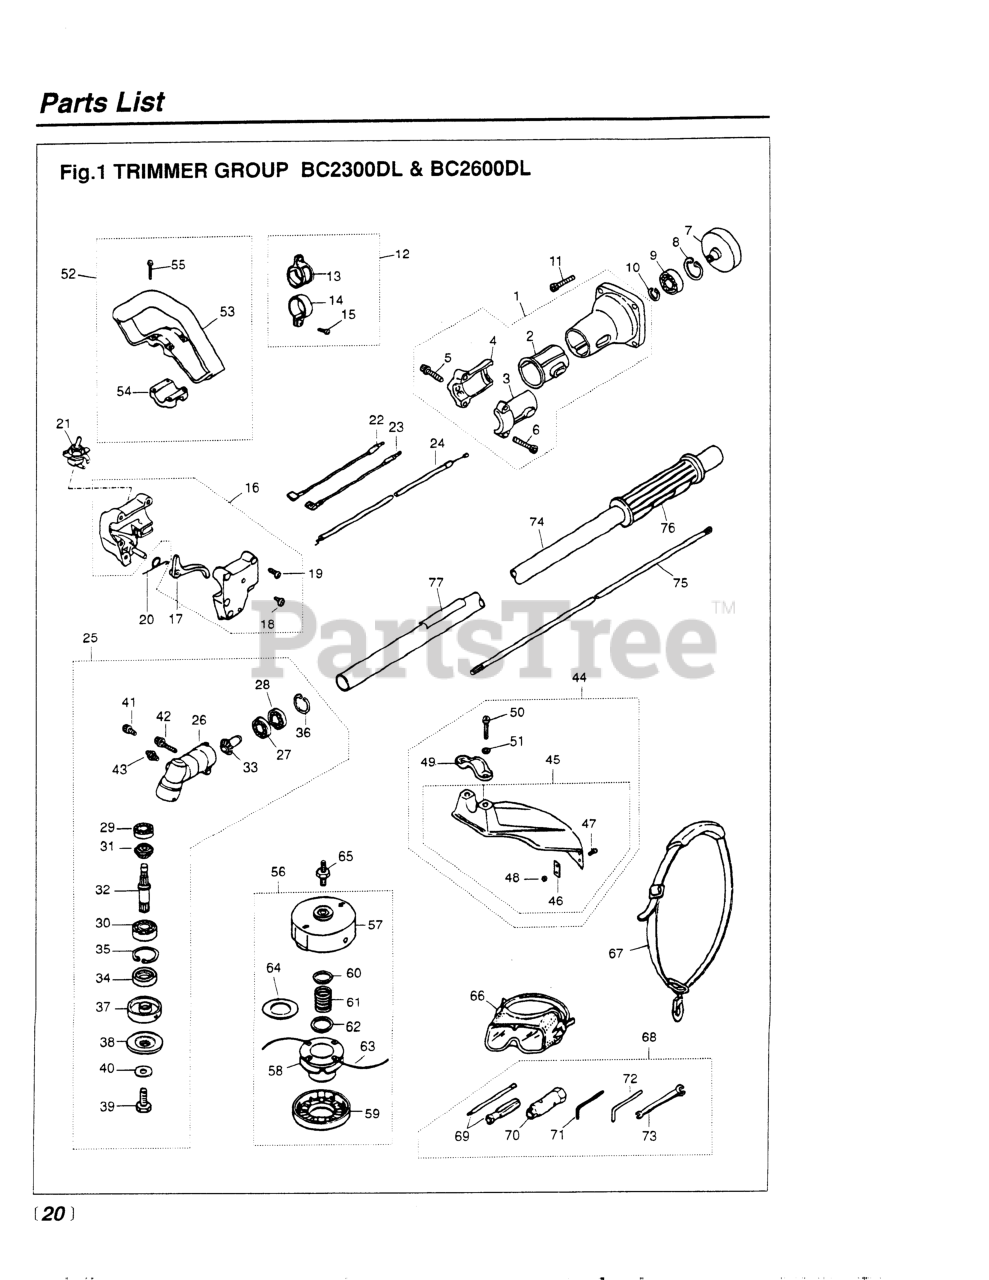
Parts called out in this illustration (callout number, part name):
2	CUSHION
3	BRACKET (USE -31211)
4	BRACKET (USE -31221)
5	BOLT (USE 3310-31720)
6	BOLT, M5 X 30
8	RING, SNAP, M28 x 1.2
9	BEARING
10	RING, SNAP (RPLS 3130-13270)
11	BOLT, M6 x 20
12	HANGER COMPLETE
13	HANGER
14	CLAMP
15	SCREW, M5 x 25
17	THROTTLE HSG & TRIGGER
18	SET SCREW, ANTI-ROTATION
19	SCREW
20	SPRING, THROTTLE TRIGGER
21	SWITCH, STOP
22	CORD, RED (LEAD WIRE)
23	CORD, BLACK (LEAD WIRE)
24	CABLE COMP (RPLS 6460- )
25	GEARCASE ASSEMBLY
26	GEARCASE
27	BEARING
28	BEARING
29	BEARING
30	BEARING
31	GEAR
33	PINION
34	SEAL, OIL
35	RING, SNAP
36	RING, SNAP
37	HOLDER (A)
38	HOLDER (B)
40	WASHER
41	BOLT, M5 x 12
42	BOLT, M5 X 25
43	FITTING, GREASE
44	GUARD ASSEMBLY
46	BLADE
47	SCREW, M5 x 12
48	NUT
49	CLAMP
50	BOLT, M6 x 1.30
51	WASHER, M6 X 15
52	HANDLE ASSEMBLY
53	HANDLE
54	CLAMP
55	SCREW, M5 x 35
56	4
59	COVER (RPLS -15130)
60	PLATE, LARGE
62	PLATE, SMALL
63	CORD
64	SPACER
65	ARBOR, 8MM
66	GOGGLE
67	SHOULDER STRAP ASSY
68	TOOL SET
69	SCREWDRIVER
71	WRENCH (TOOL)
72	BAR
73	SPANNER, 8 X 10 (RPLS 2540- )
77	LABEL, BC2300/2600DL
